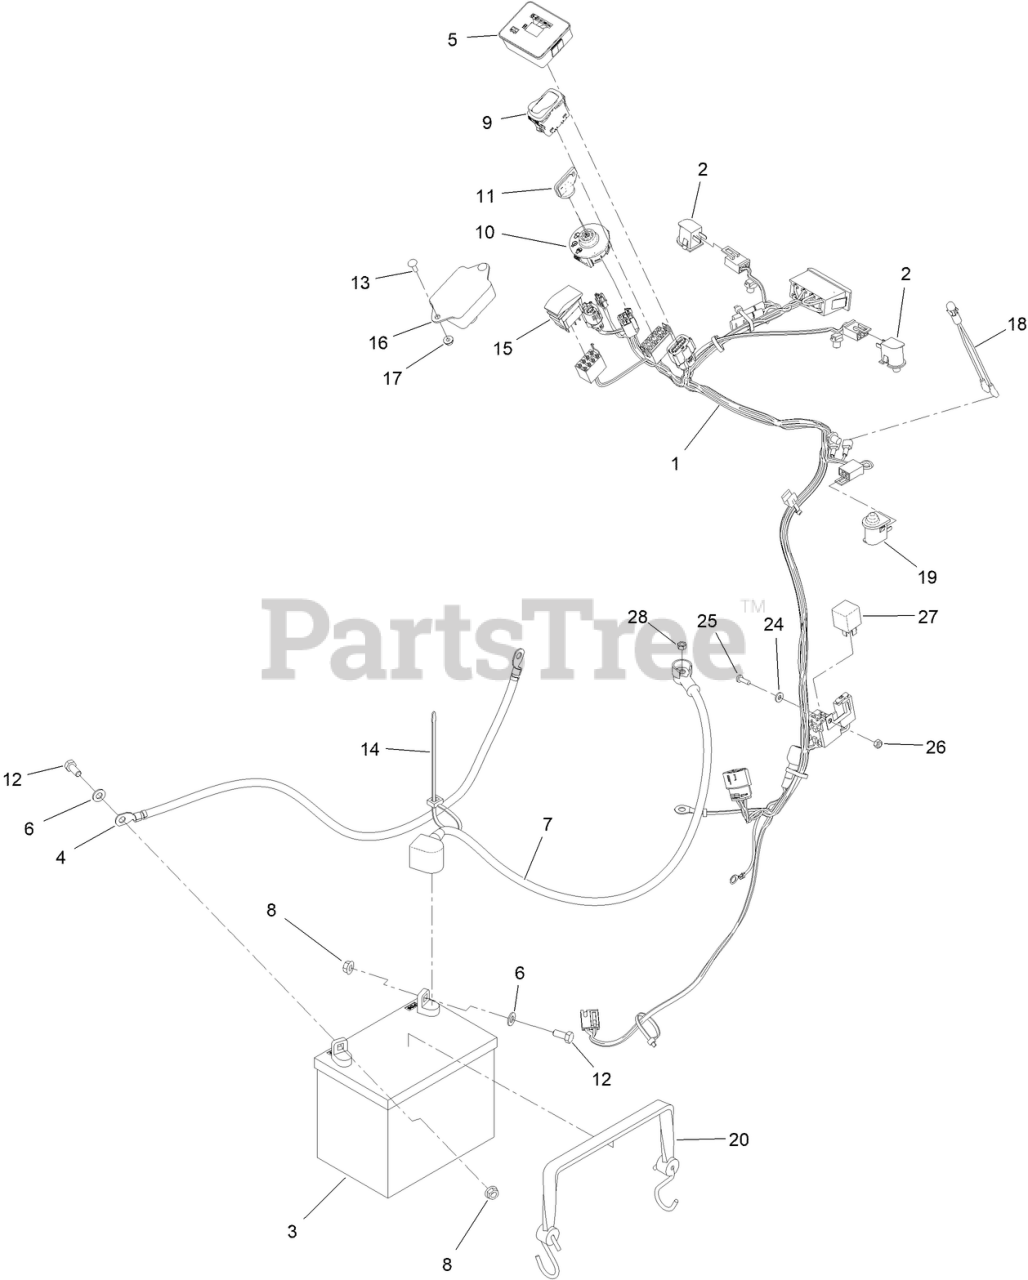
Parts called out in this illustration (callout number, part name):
1	HARNESS-WIRE, GRANDSTAND
2	SWITCH-BAIL
3	BATTERY-DRY
4	BATTERY-CABLE, BK ASM
5	MODULE-METER, HOUR
6	WASHER-PLAIN
7	BATTERY-CABLE, RD ASM
8	NUT-HHF, SMOOTH
9	SWITCH-ROCKER, (ON)-ON-OFF
10	SWITCH-IGNITION
11	KEY-IGNITION
12	SCREW-HH
13	BOLT-CARR
14	TIE-CABLE
15	SWITCH-ROCKER, ON-ON-ON
16	BOX-RESISTOR, ASM
17	NUT-LOCK, FLANGE
18	INDICATOR-LED, RED
19	SWITCH-PLUNGER
20	STRAP-RUBBER
24	WASHER-FLAT
25	SCREW-PPH
26	NUT-LOCK, NI
28	NUT-HEX
